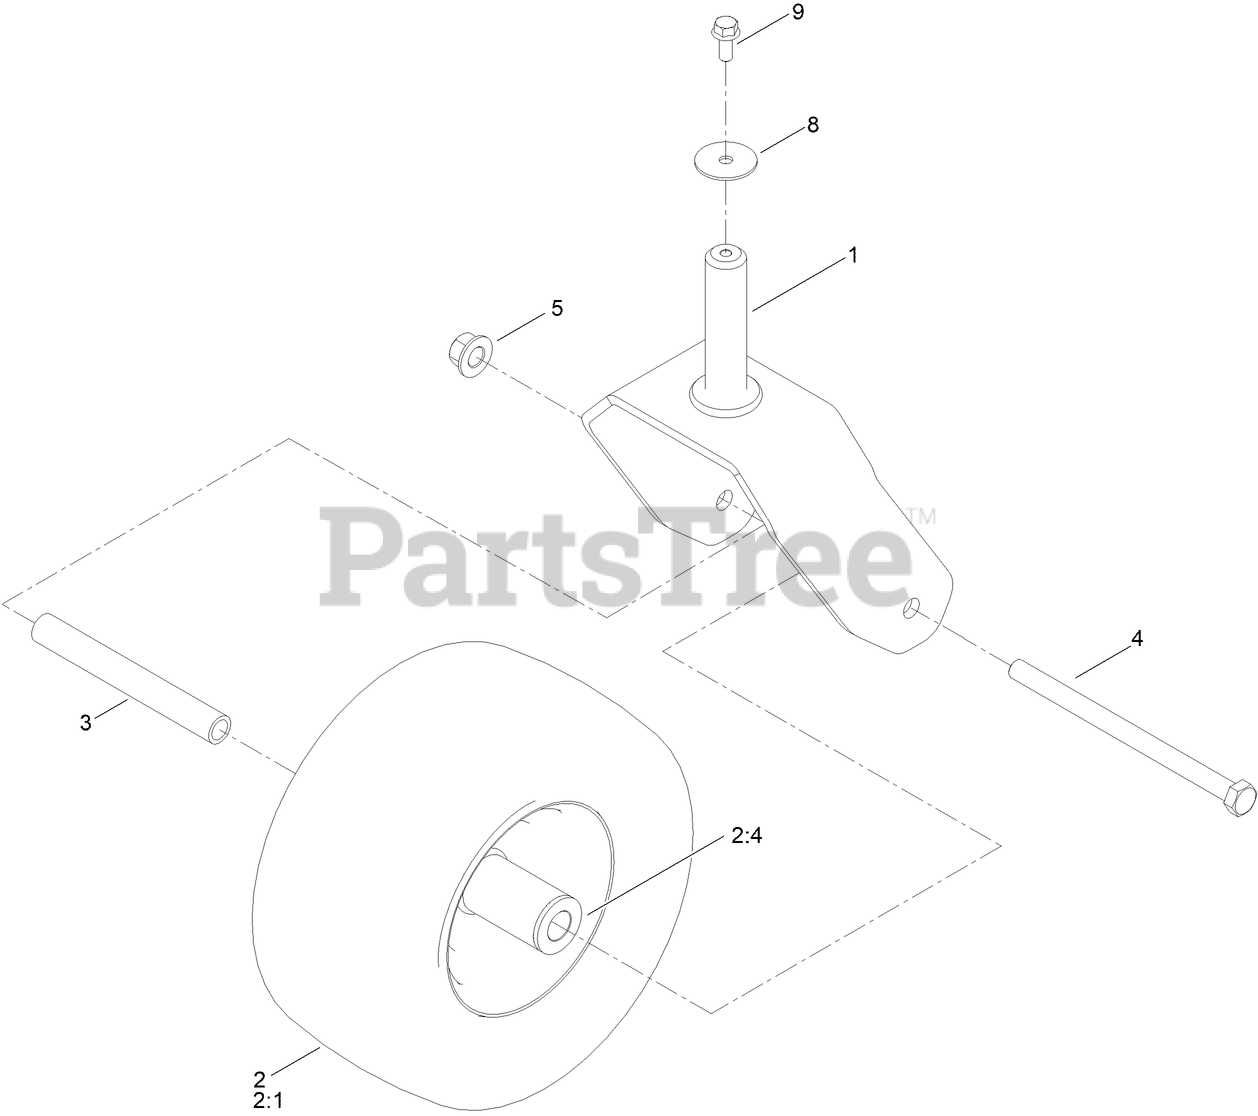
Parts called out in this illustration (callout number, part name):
1	FORK ASM
2	TIRE ASM
2:4	BUSHING-FLANGE
3	SPACER-SPANNER
4	SCREW-HH
5	NUT-HF
8	WASHER-FLAT
9	SCREW-HHF
